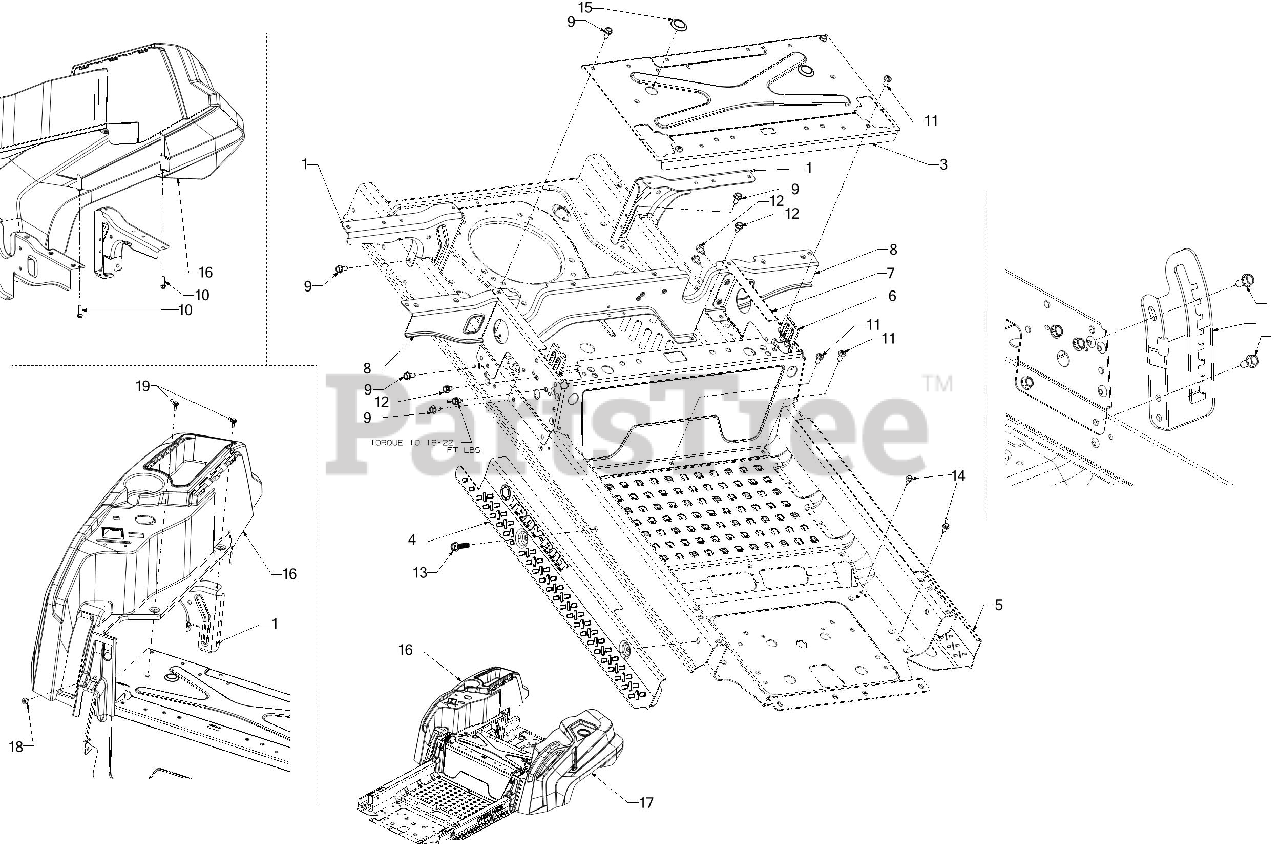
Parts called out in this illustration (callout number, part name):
1	REAR TANK BRACKET
2	HEIGHT INDEX BRACKET
3	SEATBOX TOP PLATE
4	FRAME SUPPORT (RH)
5	FRAME SUPPORT (LH)
6	LAPBAR BRACE BRACKET
7	SEAT FRAME
8	REAR SEATBOX BRACE
9	SCREW 5/16-18 x .750
10	SCREW 5/16-14 x 1
11	SCREW 5/16-18 x .750
12	SCREW 5/16-18 x .500
13	SCREW 3/8-16 X1.250
14	SCREW 1/4-20X.625
16	CONSOLE (RH)
17	CONSOLE (LH)
18	TORX SHOULDER SCREW 1/4-20
19	SHOULDER SCREW M6-1 .368 X.115
